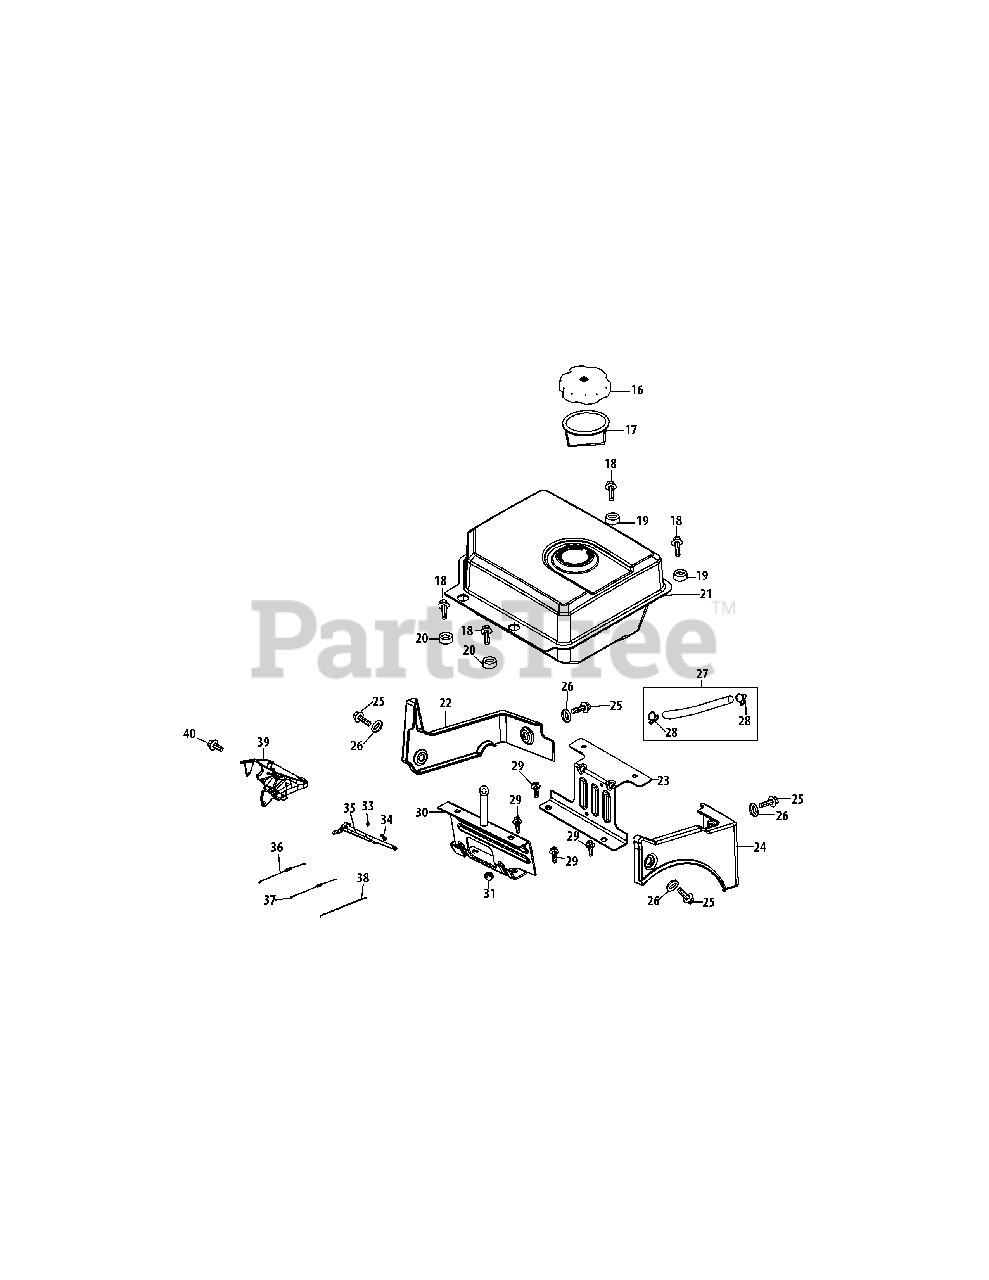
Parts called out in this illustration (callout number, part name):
16	Fuel Cap Assembly
17	Fuel Level Indicator
19	Bush Gas Tank
20	Bush Gas Tank
21	Fuel Tank Assembly
22	Left Trim Plate
23	Rear Mainting Bracket Assy.
24	Right Trim Plate
27	Fuel Hose Kit
28	Fuel Hose Clamp
30	Gas Tank Support Bracket
33	Nut M6
34	Governor Arm Bolt
36	Governor Spring
37	Throttle Linkage Spring
38	Throttle Linkage
39	Primer Bracket
